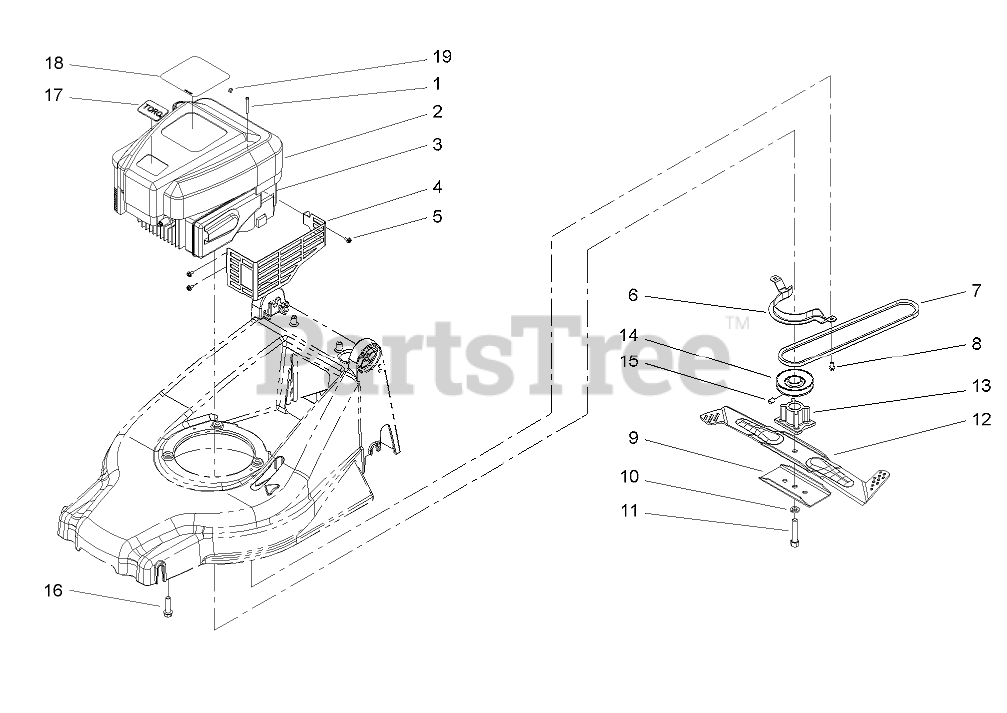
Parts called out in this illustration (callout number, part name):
1	SCREW-PPH
2	SHROUD-ENGINE
4	SHIELD-MUFFLER
5	SCREW-HWH
6	GUIDE-BELT, ENGINE
7	V-BELT
8	SCREW-HWH
9	STIFFENER-BLADE
10	WASHER-LOCK
11	BOLT-BLADE
13	RETAINER-BLADE
14	PULLEY ASM
15	SCREW-SET
16	SCREW-HWH
17	Decal
18	DECAL-ENGINE
19	STOP-ROPE
